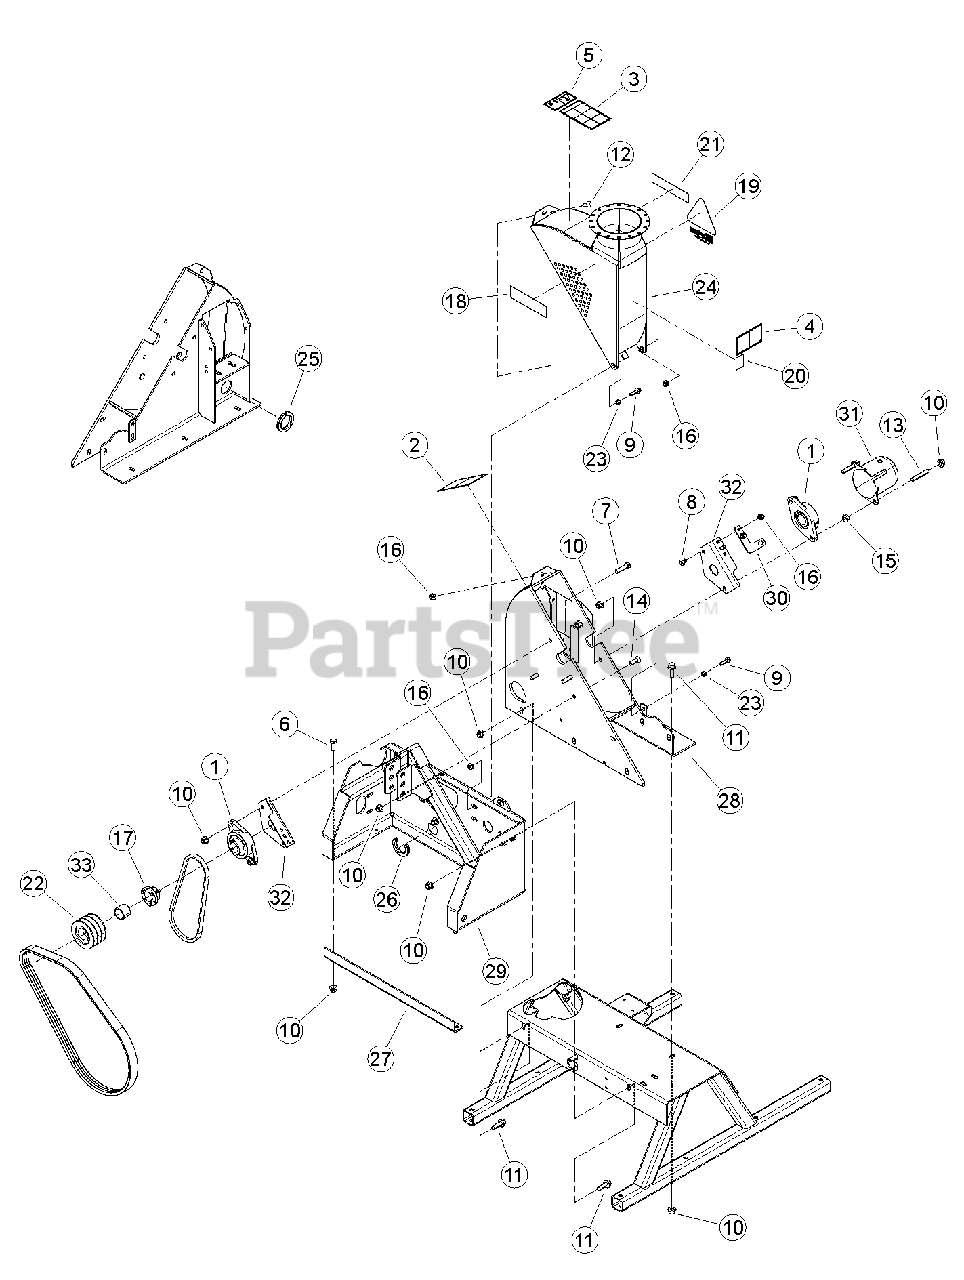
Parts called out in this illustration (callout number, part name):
1	BEARING, 1-1/2" 2-BOLT SET SCREW
2	DECAL, KNIFE ACCESS ISO
3	DECAL, OPERATING INSTRUCTIONS ISO
4	DECAL, DISCHARGE ISO
5	DECAL, MAINTENANCE ISO
6	BOLT, 1/2 X 1-1/4" GR5 HHCS NC ZP
7	BOLT, 1/2 X 2 GR5 HEX CAPSCREW ZP
8	BOLT, 3/8 X 1" GR5 CRG NC ZP
9	BOLT, 3/8 X 1-1/4 FLANGE NC
10	NUT, 1/2-13 NYLOCK FLANGE
11	BOLT, 1/2-13 X 1-1/2 GR5 FLANGE NC
12	BOLT, 3/8 X 1-1/4" GR5 CRG NC ZP
13	STUD, 1/2"-13 X 3" LG B7 ZP
14	SCREW, 1/2 X 1-1/2 FLT HD SKT
15	NUT, 1/2 SPIRAL LOCK NC ZP
16	NUT, 3/8-16 NYLOCK FLANGE
17	BUSHING, SH 1-1/2"
18	DECAL, ECHO BEARCAT 6.82 X 1.90
19	DECAL, CHIP IT
20	DECAL, ECHO BEARCAT QR CODE
21	DECAL, MODEL CH5540HM
22	SHEAVE, 3B3.8 SH
23	BUSHING
24	WELDMENT, CHIPPER TOP
25	TRIM, SLOT EDGE COVER
26	TRIM, SLOT EDGE COVER
27	BRACE, 3 PT BOTTOM
28	WELDMENT, CHIPPER FRAME
29	WELDMENT, CHIPPER HITCH
30	BRACKET, SENSOR
31	CAP, LARGE SHAFT
32	PLATE, BEARING MOUNT
33	SPACER, 1.75 X 1.32 X .120
